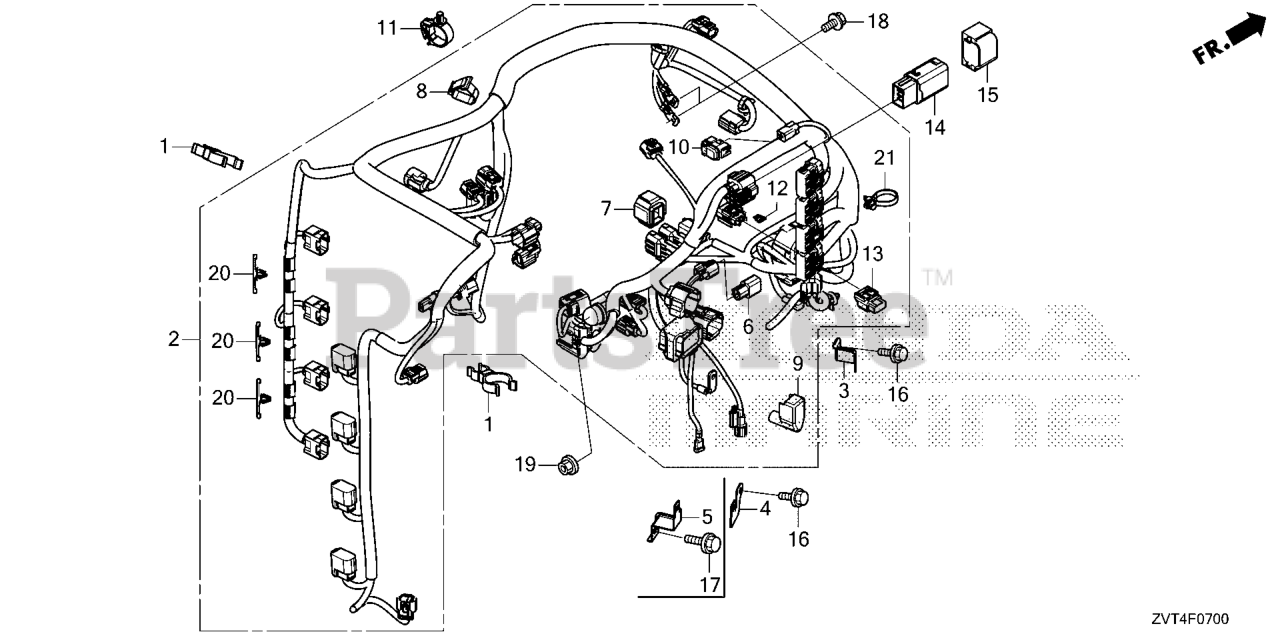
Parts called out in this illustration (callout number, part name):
1	CLAMP, HOSE
2	HARN, MAIN WIRE
3	STAY, CONNECTOR
4	STAY, CONNECTOR
6	TERMINATOR ASSY.
7	SUSPENSION, CONNECTOR
8	BAND, WIRE
9	COVER B, TERMINAL (L)
10	CAP, DUMMY (WPC 4P 090 M) (RED)
11	CLAMP, ENGINE SUB-WIRE
12	FUSE, BLADE (3A)
13	COVER ASSY., FUSE
14	RELAY ASSY., SENSING
15	CUSHION, RELAY
16	BOLT, FLANGE (6X14)
18	BOLT, FLANGE (6X12)
19	NUT-WASHER (6MM)
20	CLIP, WIRE HARNESS
21	CLIP, HARNESS BAND (145MM) (BLACK)
